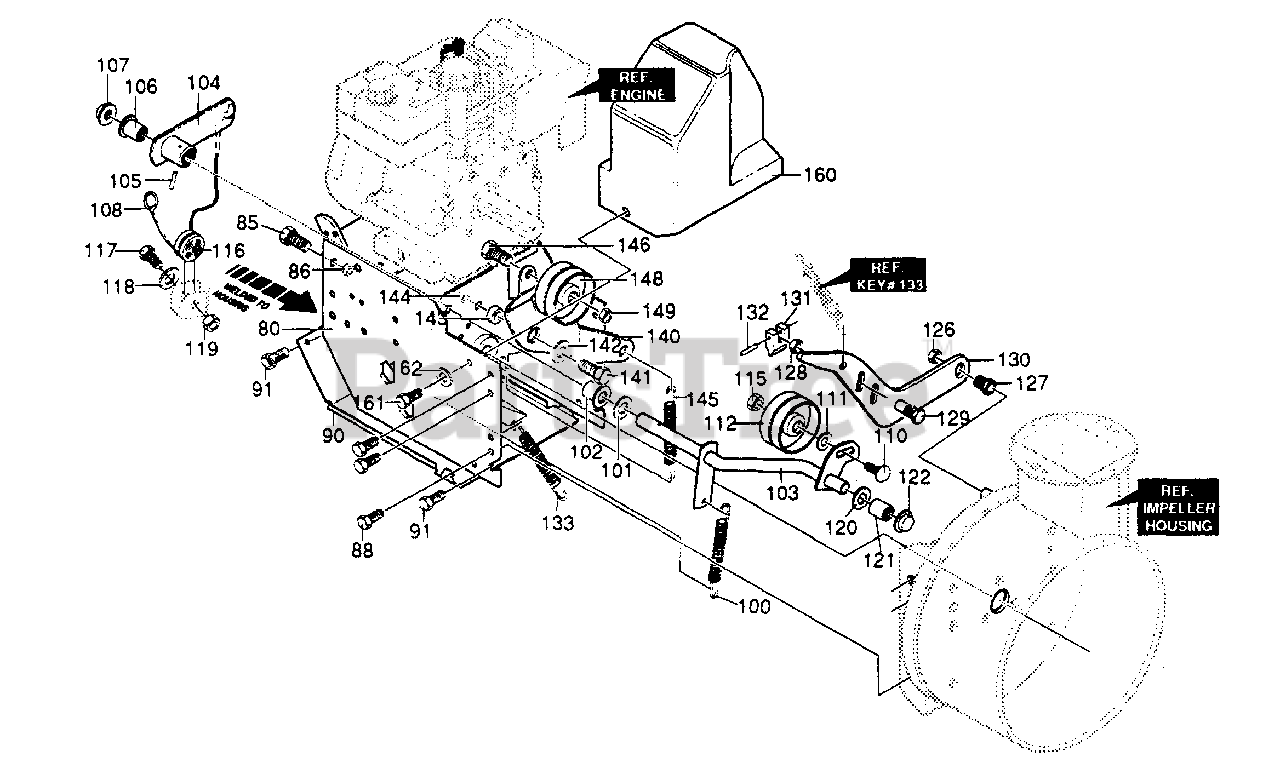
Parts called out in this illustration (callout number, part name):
80	FRAME, ASSY ENGINE MT 16"
85	SCREW, 5/16-241.00 HHC
86	NUT, 5/16-24 HEXWDFLLK
88	SCREW, 5/16-18x.50 WAHHTAP
90	COVER, BOTTOM WHEEL DR
91	SCREW, 1/4-20x.63 WAHHTAP
100	IDLER SPRING
101	FLATWASHER,.53x1.00x.063
102	BEARING, FLANGE
103	ASSY, SHAFT AUG CLUTCH
104	LEVER, ASSY AUGER CLUTCH CABLE
105	PIN, SPRING. 165DIAx.88LG HD
106	BEARING, FLANGE
107	NUT, 1/2 PUSHON
108	CABLE, .205 EYE 6.125 LG
110	CARR. BOLT, 3/8-16x1.25
111	FLATWASHER, .406x.81 x.065
112	PULLEY, IDLER
115	NUT, 3/8-16 HXCTRLKJAM
116	SPOOL, CABLE AUGER CLUTCH
117	SCREW, 1/4-200.75
118	FLATWASHER, .281x.63x.065
119	NUT, 1/4-20 REGHEXCTRLK
120	FLATWASHER, .53x1.090x.063
121	BEARING, SLEV
122	NUT, 1/2 PUSH ON
126	NUT, 9/16-18 HEXJAMCTRLK
127	BOLT, BRAKE ARM 9/16-18
128	NUT, 1 /2-20 JAM
129	BOLT-BRAKE ARM ADJ
130	BRAKE ARM BRACKET
131	PAD, AUGER/IMPELLER BRAKE
132	PIN, SPRING. 165DIAX.88LG
133	SPRING, TENSION RETURN
140	LEVER, IDLER ARM TRACTION
141	SCREW 5/16-18X.75
142	FLATWASHER.328X1.25X.075
143	BUSHING, IDLER LEVER
144	NUT, 5/16-18 HEXNYL
145	IDLER SPRING
146	SCREW 3/8-16X1.25
148	PULLEY, IDLER
149	NUT 3/8-16 HXCTRLKJAM
160	BELT COVER
161	SCREW 1/4-20X.63 WATAP
162	FLATWASHER.281 X.63X.065
